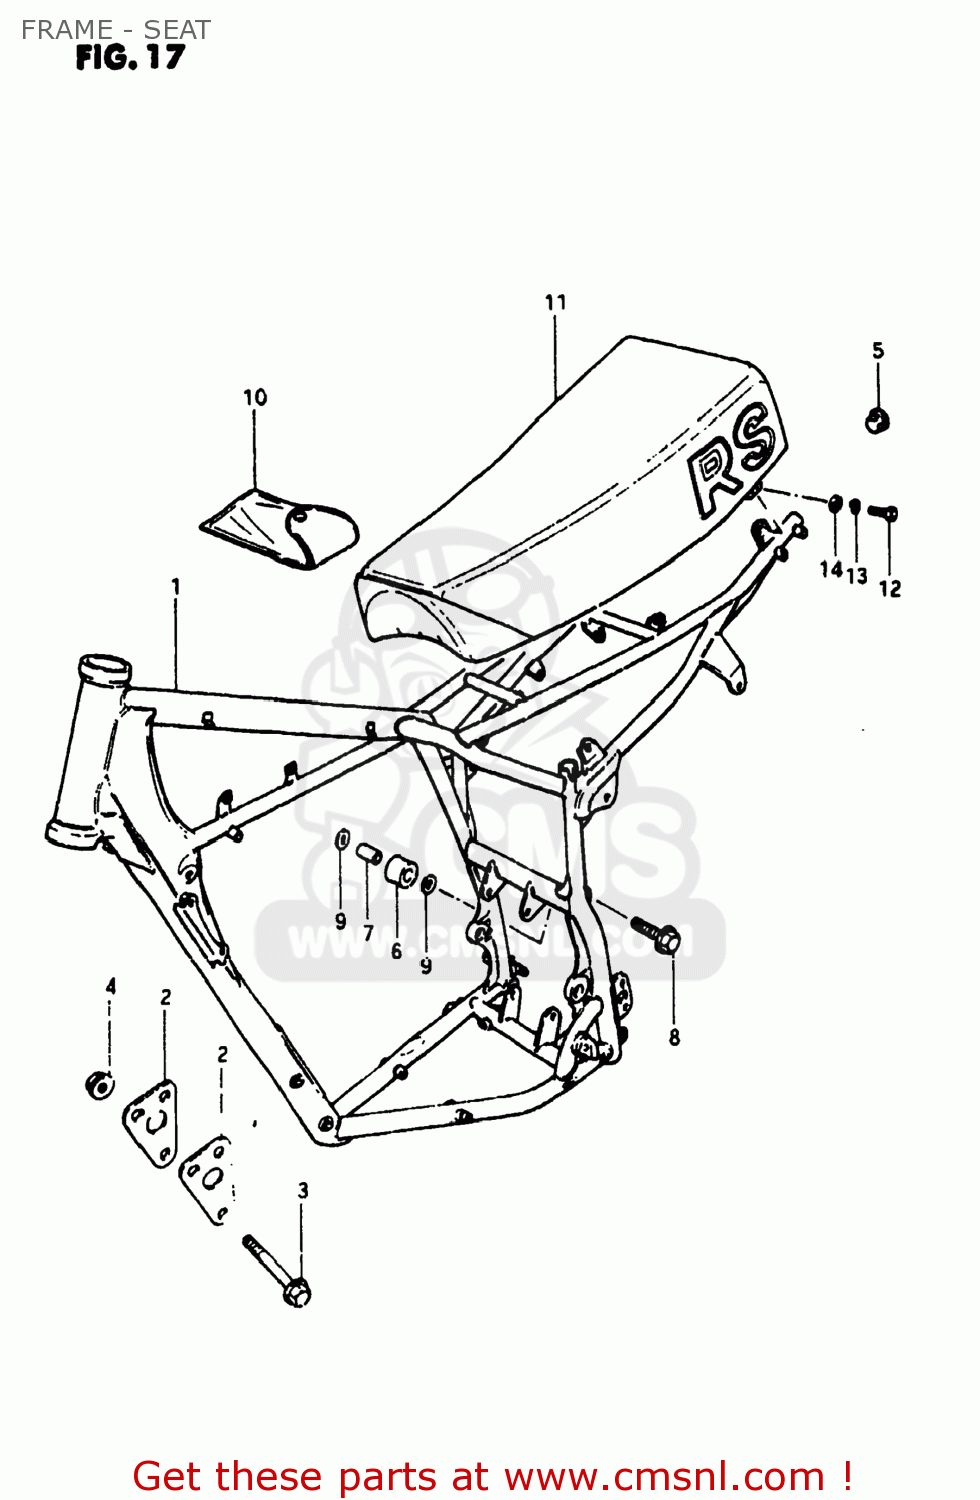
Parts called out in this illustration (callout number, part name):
1	FRAME
2	PLATE,ENGINE MOUNTING
3	BOLT(8X67)
4	NUT
5	PLUG(OD:19)
6	ROLLER,CHAIN CONTROL
7	SPACER,CHAIN LENGTH ROLLER
8	BOLT(8X45)
9	WASHER
10	TOOL SET
11	SEAT ASSEMBLY
12	BOLT
13	LOCK WASHER
14	WASHER
